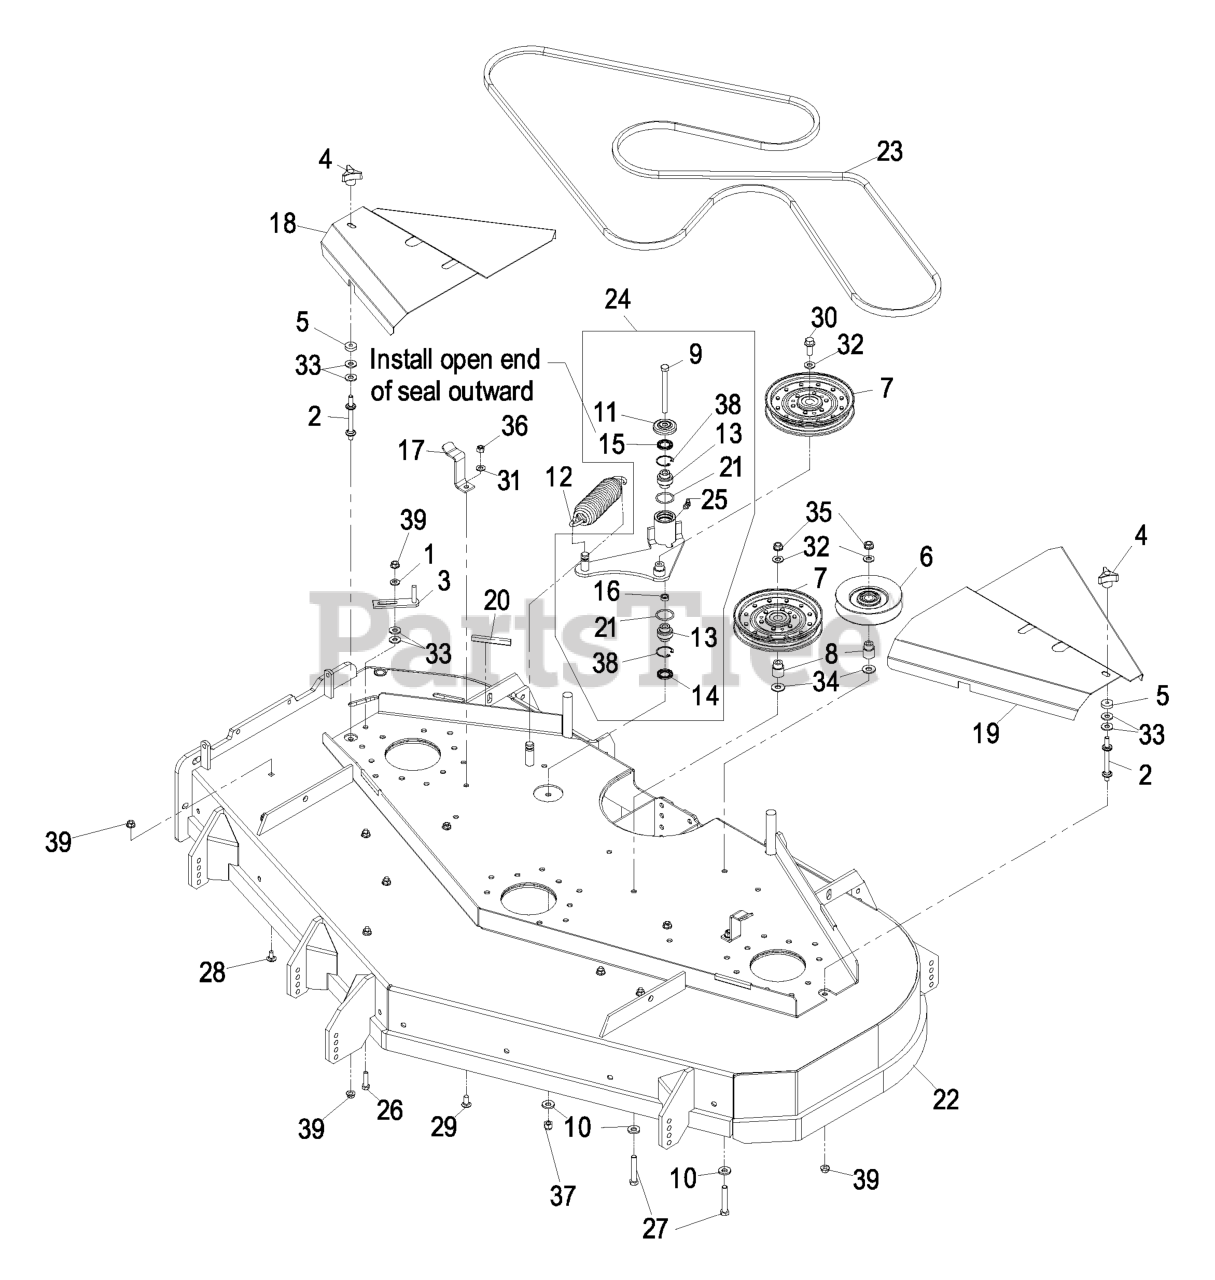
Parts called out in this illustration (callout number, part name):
1	WASHER-SPRING
2	STUD-SHIELD, BELT (SHORT)
3	GUIDE-BELT
4	KNOB-3 PRONG
6	PULLEY-IDLER
8	BUSHING-IDLER
9	SCREW-HH
10	WASHER-BELLEVILLE
11	GUARD-TOP
13	BEARING-SPHERICAL
14	SEAL-LIP, DOUBLE
15	SEAL-LIP, SINGLE
17	LATCH,BELT SHIELD
18	SHIELD, BELT RH 605 W/DEC
19	SHIELD, BELT LH 605 W/DEC
20	STRIP-SEAL
22	ASM, DECK 605 W/DECALS
23	BELT,BLADE DRIVE
24	KIT, IDLER ARM W/BEARINGS
25	FITTING-GREASE, 90 DEG
26	SCREW-HH
27	SCREW-HH
28	SCREW-CARR
29	SCREW-CARR
30	SCREW-HHF
31	WASHER-PLAIN
32	WASHER-FLAT
33	WASHER-FLAT
34	WASHER-FLAT
35	NUT-HHF, WHIZ
36	NUT-LOCK, NI
37	NUT-LOCK, NI
38	RING-SNAP
40	Asm, Deck Complete 60"
